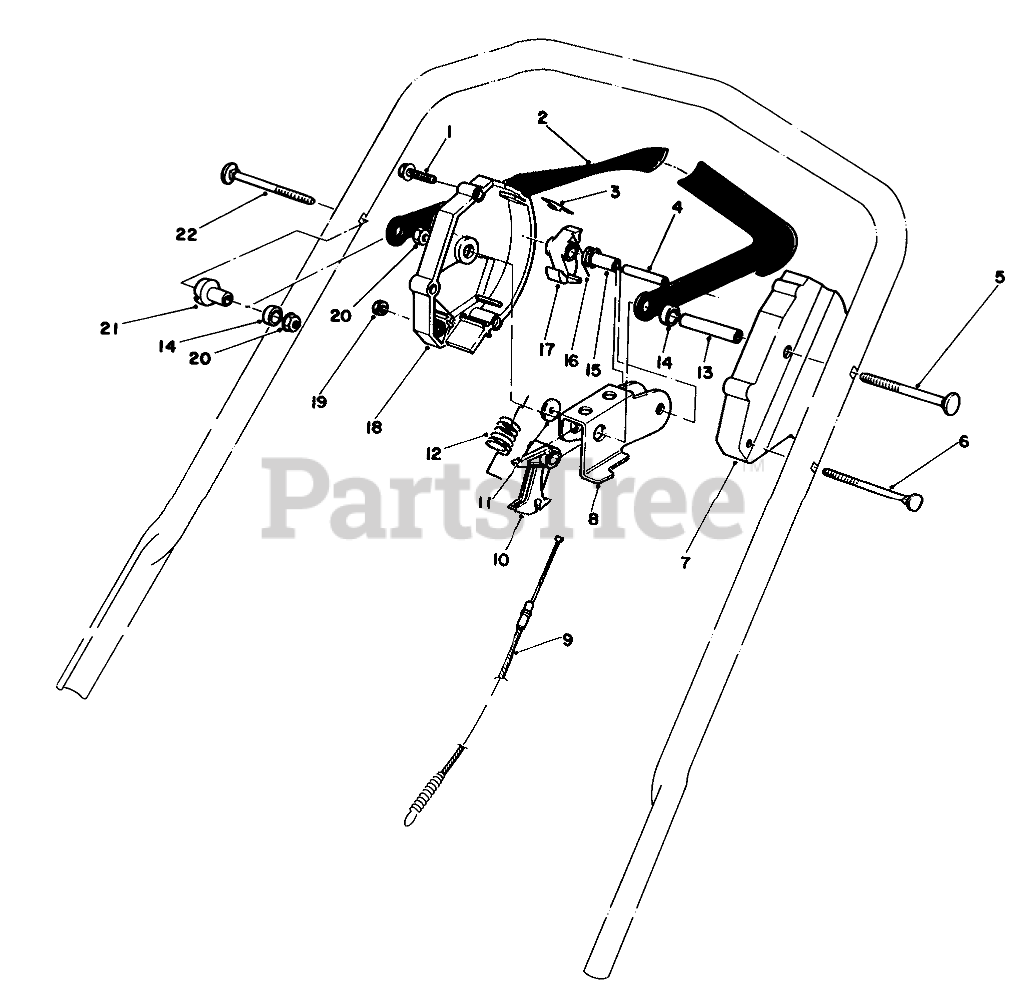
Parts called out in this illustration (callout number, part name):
1	SCREW-HWHTF
2	Bar-Control
3	LEAF SPRING
4	PIN-ROLL, SLOTTED
5	5/16-18 X 3 HNDLE SCREW
6	HANDLE SCREW
7	HOUSING-CONTROL, LH
8	Rocker
9	Cable-Clutch
10	LEVER-CABLE
11	PLASTIC WASHER
12	Spring-Detent
13	TUBING-SPACER
14	SPACER-NYLON
15	SPACER
16	SPRING-TORSION
17	HOOK-CONTROL
18	Housing Control R.H.
19	NUT-LOCK, NI
20	NUT-LOCK, NI
21	SPACER-SUPPORT
22	5/16-18 X 2 HNDLE SCREW
